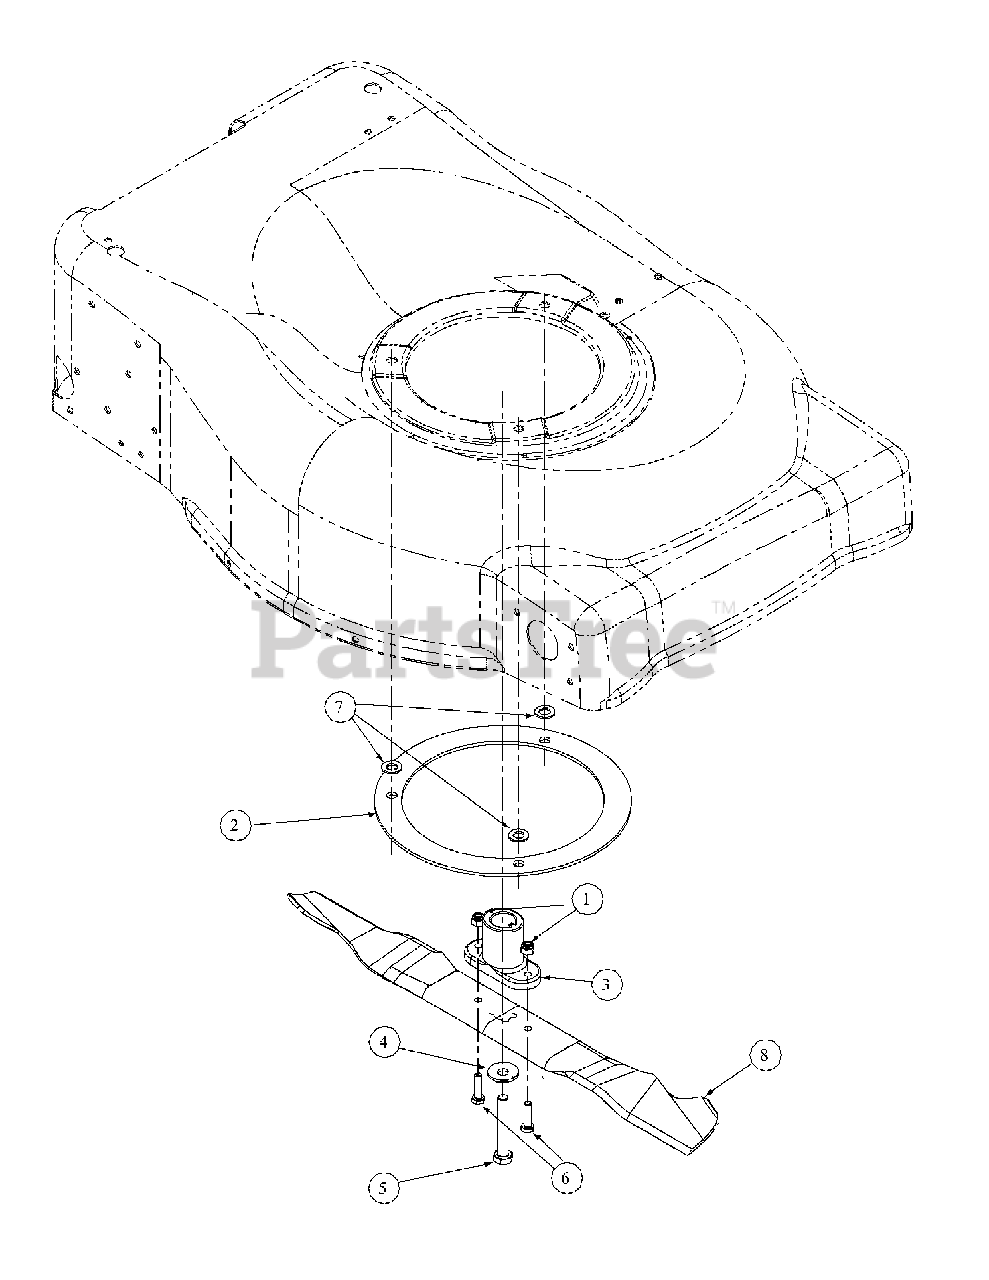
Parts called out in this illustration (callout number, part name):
1	Hex Nut, 1/4-20
2	Engine Mount Support Plate
3	Blade Adapter, 6 x 2.15 W/Star
4	Bell Washer, .396 x 1.140 x .095
5	HHCS: 3/8-24, 2.50,
6	HHCS, 1/4-20, 1.00,
7	Flat Washer, 3/8X.738X .063
8	Mulching Blade w/Star21"
9	5.5 hp Kawasaki Engine
